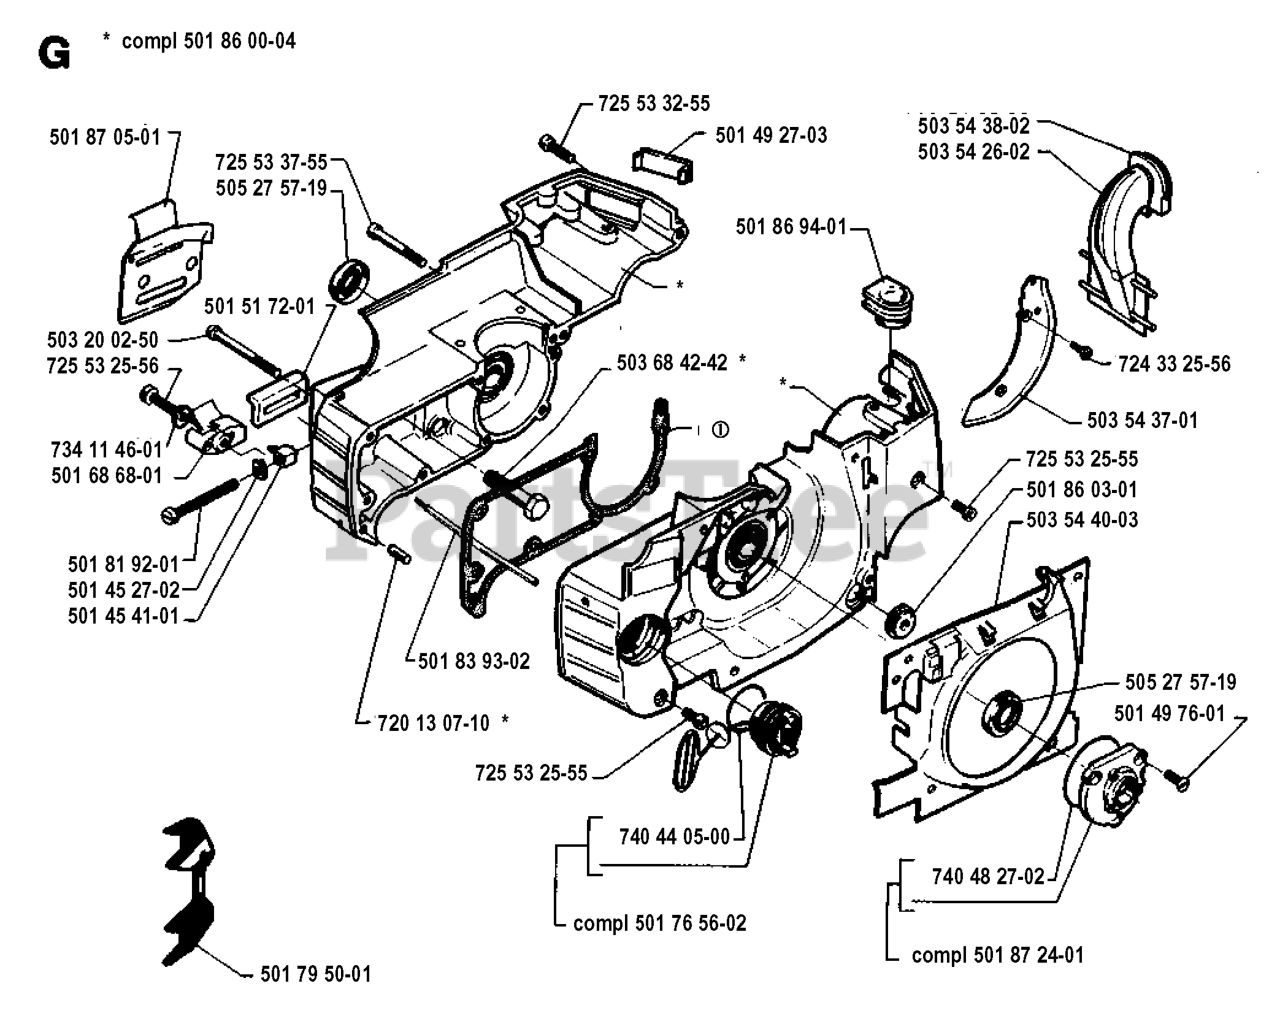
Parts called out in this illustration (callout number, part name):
2	VALVE STEM LT
3	RIM ASM 6" FRONT SILVER
4	TUBE.5.3/4.5/6
5	TIRE.15X6-6.TURF.MASTER.FRONT
6	FITTING LT
7	BEARING T
8	CAP, AXLE BLK
9	TIRE.20X10-8.TURF.MASTER.REAR
10	TUBE
11	RIM ASM 8" REAR SILVER
